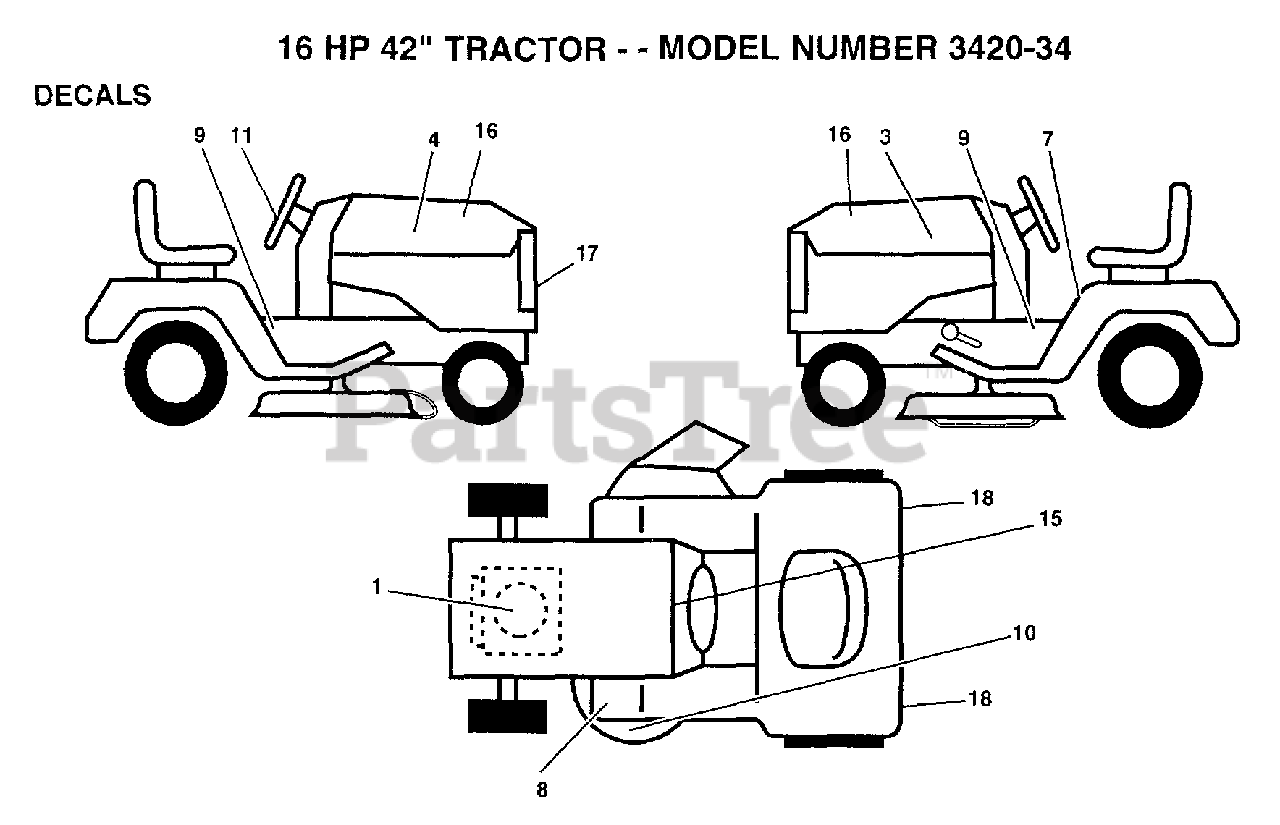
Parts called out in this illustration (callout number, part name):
1	DECAL.ENG.272090
3	HOOD DECAL LH
7	DECAL
9	DECAL CHASSIS
15	DECAL.DASH.INST.
16	NAMEPLATE LOGO
17	GRILL DECAL
18	REFLECTOR-TAIL YT
